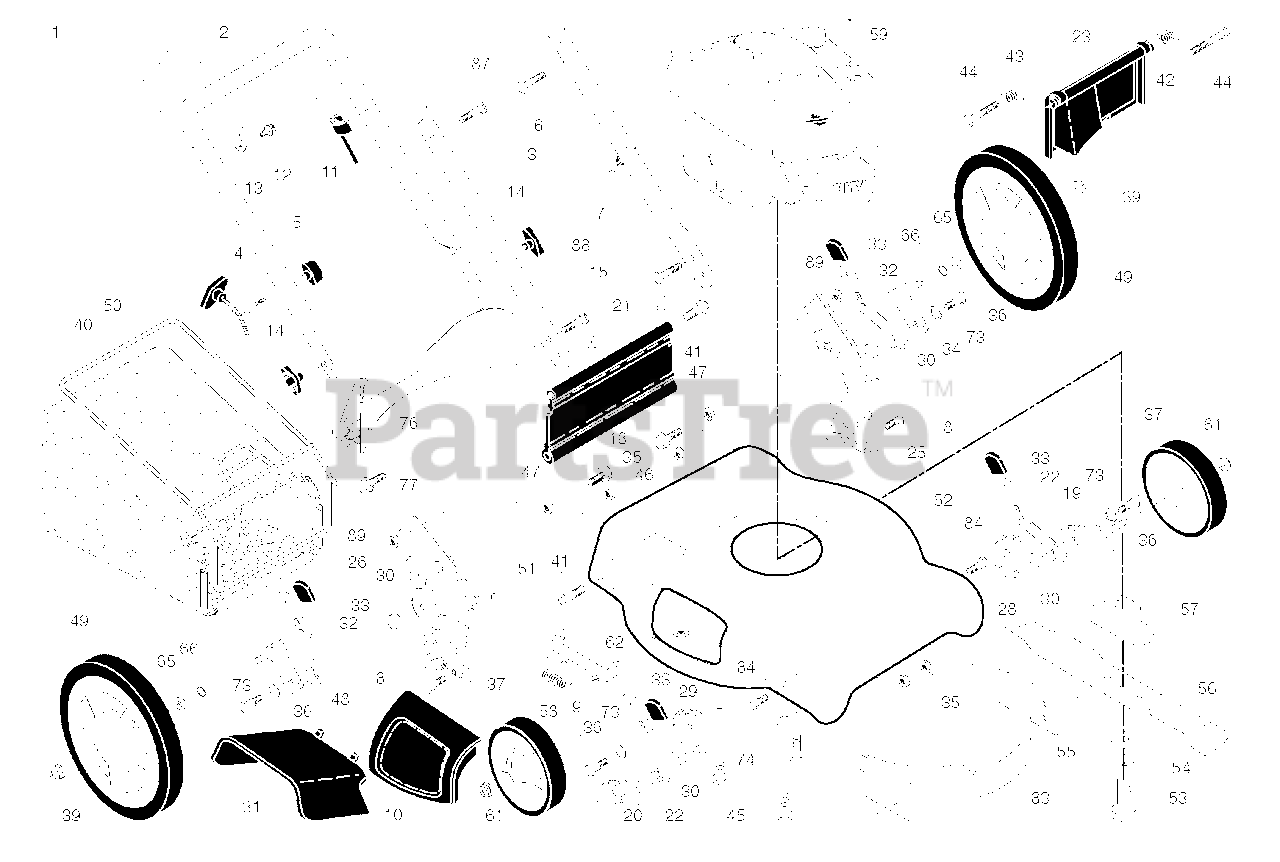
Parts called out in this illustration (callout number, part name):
1	BAIL.CONT.D.STRAIGHT.PUSH.BLK
2	HANDLE.UPPER.ECONOMY.BLACK
3	HANDLE.LOWER.DOME.BT.BLACK
4	Rope Guide, Blk Zinc Chrom
5	T-KNOB.NEW ROPE GUIDE
6	BOLT, HANDLE 5/16-18X1.75
7	TIE GUIDE
8	BOLT
9	BRACKET.ASM.HOUSING.EZ.MUL
10	MULCH DOOR
11	CABLE.MZR.RATO.22"LOW.
13	BRACKET.UPSTOP.RT
15	HAIRPIN COTTER
18	SCREW 1/4X20
19	AXLE ARM ASSY FRONT LH
20	AXLE ARM ASSY FRONT RH
21	SKIRT.REAR.21.PUSH
22	SELECTOR SPRING, FRONT
23	REAR DOOR ASSY
25	BRACKET.ASM.HANDLE.HW.21.LT.BL
26	BRACKET.ASM.HANDLE.HW.21.RT.BL
28	BRACKET.ADJ.5.RTAB.LG.HOLE.ABS
29	BRACKET.ADJ.5.LTAB.LG.HOLE.ABS
30	SPACER.HEIGHT.ADJUSTER
31	CLIP ON DISCHARGE GUARD
32	SPRING.SEL.22.ECON.HI-WHL.RATO
34	Axle Arm Assembly, .Lr.5/9.Pos.Bzp
35	NUT.FLANGE.HEX.5/16X18.BLACK
36	SHOULDER BOLT 5/16-18
37	WHEEL.7X1.75.5SPK.BRK.BLACK
39	NUT.HEX.FLANGE.3/8-16.LOCKNUT
40	FRAME.BAG.21.REAR.DOMED.PUSH
41	SCREW.1/4-20X21/4.HEX.
42	SPRING.LH.22.REAR.DOOR.EZ.EMPT
43	SPRING.RH.22.REAR.DOOR.EZ.
45	BOLT 3/8-16X1-1/8
46	No Step Decal
47	NUT.LOCK.5/16-18
48	Axle Arm Assembly, RR 5/9 Pos BZP
49	WHEEL.12X1.75.5SPK.BRK.BLACK
50	GBAG.24710612.BLK.WEAT
51	ROD.HINGE.COMBI-C
53	SCREW, HEX HD 3/8-24 X 1-3/8
55	WASHER,HARDEN
56	BLADE.21.PUSH/RWGD/FWGD
57	ADAPTOR.BLADE.7/8
58	TORSION SPRING
61	NUT.HEX.FLANGE.3/8-16.LOCKNUT
62	LOCKNUT.NYLOC.1/4-20
65	WASHER PM
66	O-RING..070X.487.NEOPRENE
73	WASHER.CURVED.CYLINDRICAL
74	WASHER.ENGINE.BZP
76	BAFFLE.REAR.PLASTIC.21.RD.ECON
77	SCREW.HX.13X.750
83	BAFFLE.FRONT.21.DOME.US
84	BOLT.5/16HEX.WHS.HD
87	PLUG.PLASTIC.7/8".14-20.GAUGE
88	Carriage Bolt, 5/16-18 X 5/8
89	LOCKNUT-FLANGE 5/16-18
